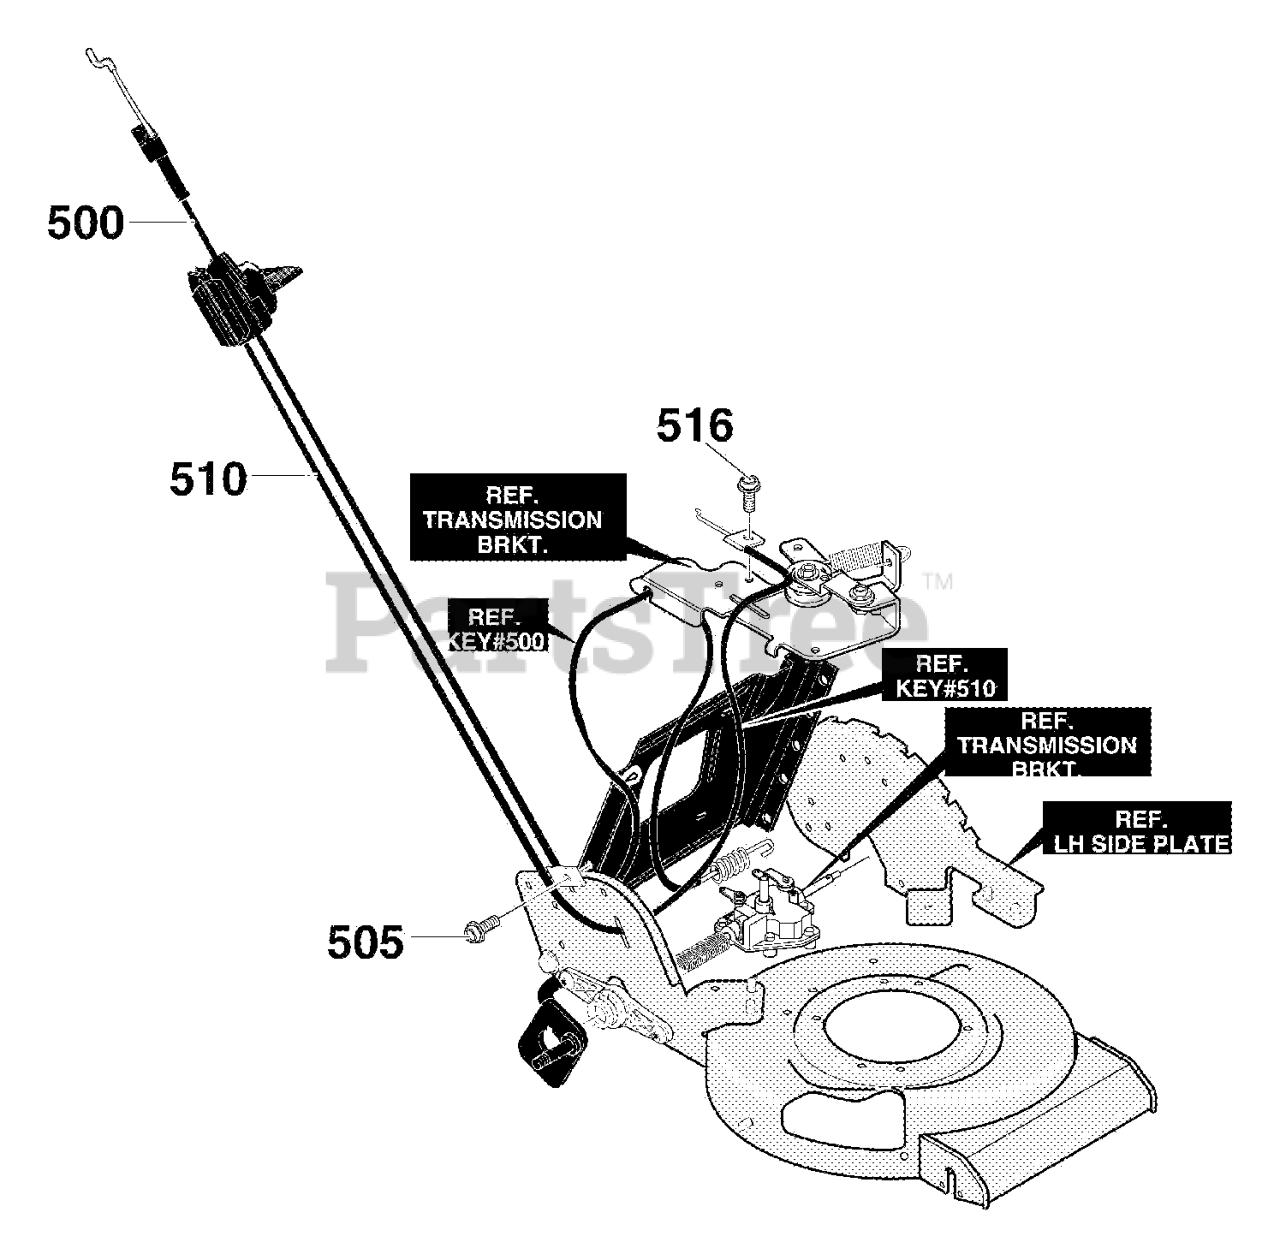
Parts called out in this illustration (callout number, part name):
500	Drive Cabk Assy.
505	SCREW, #10-16x.50
510	CABLE, Shifter Speed Cont
516	SCREW, #10-32X.62
